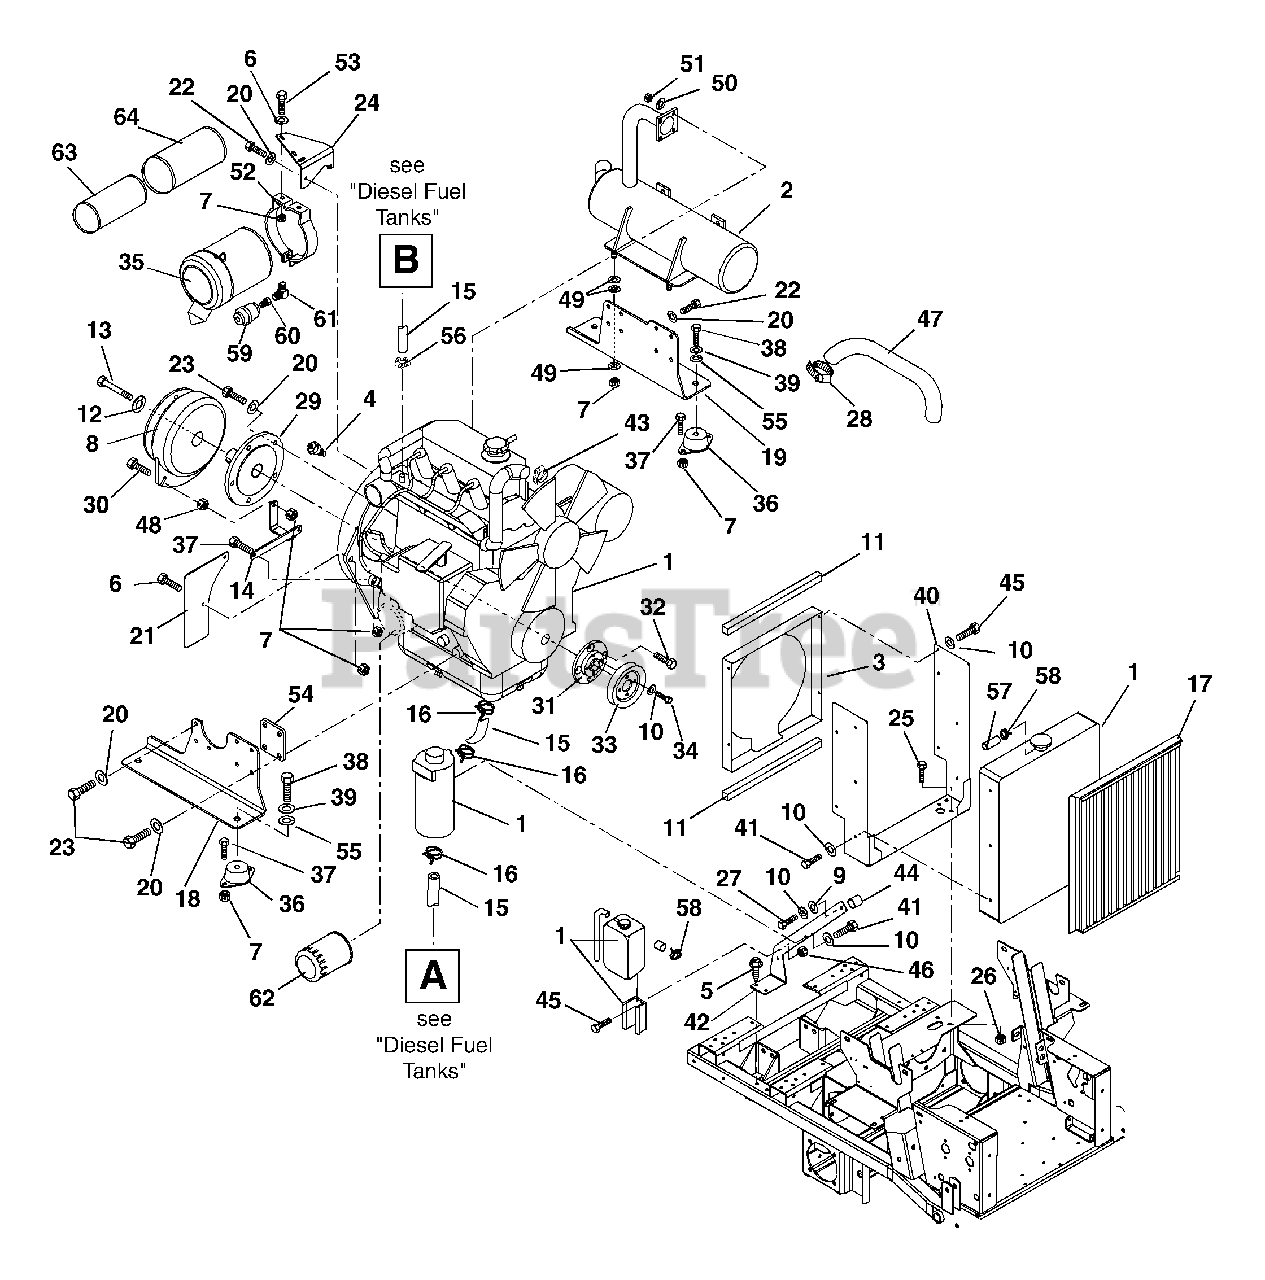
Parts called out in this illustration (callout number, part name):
1	ENGINE, 27HP DIESEL (DAIHATSU)
2	MUFFLER
3	WMT, RADIATOR SHROUD
4	SENDER, TEMPERATURE
5	@SCR-TAP .38-16X.75 HWH TR YWZ
6	@BLT-HEX .31-18X.75 GR5 YWZC
7	@NUT-LK-TOP-FLG .31-18 YWZC
8	CLUTCH, ELECTRIC (WARNER)
9	@WSHR-FL-STL.281X.62X.065 YWZC
10	@WSHR-LK .25X.062 REG YWZC
11	SEAL, TRIM-LOK BULK .06 BBL 1'
12	@WSHR-LK .44X.109 REG YWZC
13	BLT-HEX .44-20X2.50 GR5 YWZC
14	STABILIZER, CLUTCH
15	HOSE,5/16 ID
16	CLAMP, HOSE WIRE .520/.550
17	SCREEN, RADIATOR (DIESEL)
18	MOUNT, ENGINE RH (DIESEL)
19	MOUNT, ENGINE LH (DIESEL)
20	@WSHR-LK .31X.078 REG YWZC
21	GUARD, FLYWHEEL
22	@BLT-HEX M8-1.25X20 YWZC
23	BLT, HEX M8-1.25X25 GR8.8YWZC
24	BRKT, AIR CLEANER - BLACK
25	@BLT-HEX .38-16X1.00 GR5 YWZC
26	@NUT-LK-TOP-FLG .38-16 YWZC
27	@BLT-HEX M6-1.00X45 YWZC
28	CLAMP,2.25 DIA. HOSE
29	SHAFT, STUB (BRIGGS-DIESEL)
30	@BLT-HEX .31-18X1.50 GR5 YWZC
31	ADAPTER, SHEAVE (DIESEL)
32	BLT, FSCHS M8-1.25X25
33	SHEAVE, POLY V 1.000 X 3.25
34	@BLT-HEX .25-20X.75 GR5 YWZC
35	AIR CLEANER ASSEMBLY
36	MOUNT, ENGINE, VIBRATION ISO
37	@BLT-HEX .31-18X1.00 GR5 YWZC
38	BLT-HEX .50-20X1.00 GR5 YWZC
39	@WSHR-LK .50X.125 REG YWZC
40	WMT, RADIATOR MOUNTING BKRT
41	@BLT-HEX M6-1X16 YWZC
42	BRKT, OVERFLOW MOUNTING - BLK
43	CLAMP-HOSE 1.50X.81X1.42
44	SPACER .328 X .76 X 1.01
45	@BLT-HEX .25-20X.75 GR5 YWZC
46	@NUT-LK-TOP-FLG .25-20 YWZC
47	HOSE, AIR CLEANER
48	@NUT-HEX .31-18 YWZC
49	@WSHR-FL-STL.38X.875X.083 YWZC
50	@WSHR-LK .31X.078 REG YWZC
51	NUT-HEX M8-1.25 YWZC
52	BRACKET, AIR CLEANER MOUNT
53	@WSHR-FL-STL.38X.875X.083 YWZC
54	SPACER, ENGINE MTG (DIESEL)
55	@WSHR-FL-STL.531X1.06X.095YWZC
56	CLAMP, HOSE, IDEAL 6202 SIZE 4
57	GAS LINE-BULK 1/4" I.D.
58	CLAMP-HOSE WIRE .490/.510X.116
59	FILTER MINDER
60	NIPPLE, 1/8"NPT
61	ELBOW,ADAPT.90 DEG.BRS 1/8X1/8
62	FILTER, OIL
63	ELEMENT, INNER SAFETY
64	ELEMENT, OUTER PRIMARY
